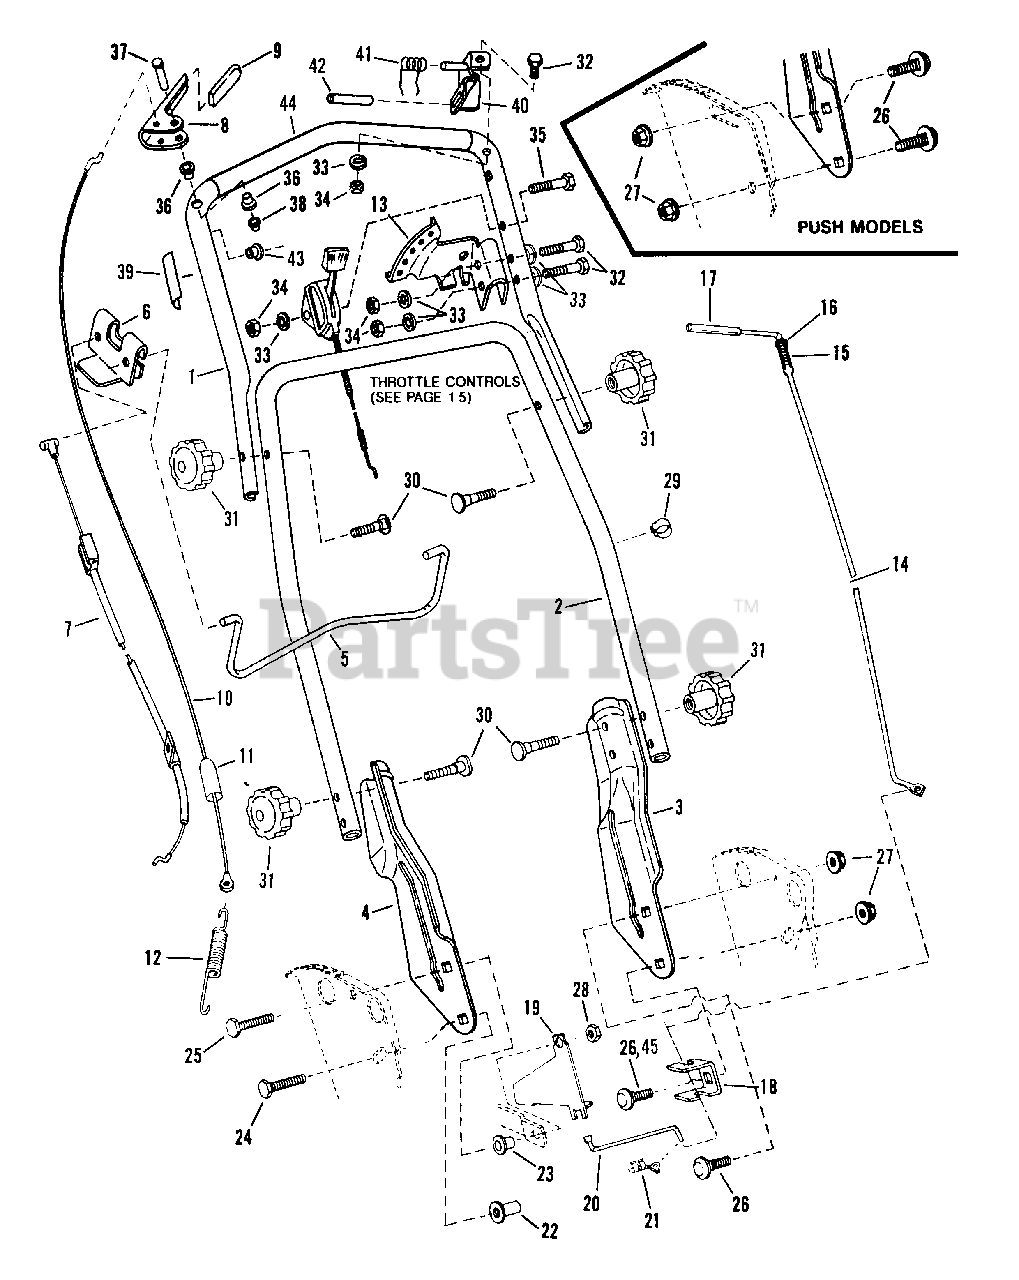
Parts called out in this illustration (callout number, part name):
1	HANDLE, Upper
2	HANDLE, Middle
3	HANDLE, Lower Left Hand
4	HANDLE, Lower Right Hand
5	CONTROL, Blade
6	CLIP, Blade Control
7	CABLE, Blade Control
8	HANDLE, Wheel Drive
9	GRIP, Wheel Drive Handle
10	CABLE, Clutch Pull (Z-BEND)
11	COVER, Vinyl
12	SPRING, Clutch
13	SECTOR, Speed
14	LEVER, Speed Control
15	SPRING, Speed Control
16	WASHER, 3/8" Flat
17	GRIP, Speed Control Handle
18	ANCHOR, Speed Control
19	GUIDE, Lower V-Belt
20	ROD, Transfer
21	CLIP, Transfer Rod
22	TEE-NUT, 5/16-18
23	BUSHING, Differential
24	BOLT, 5/16-18 x 3/4 Flange Lock
25	CAPSCREW, 5/16-24 x 1
26	BOLT, 5/16-18 x 5/8 Carriage
27	NUT, 5/16-18 Hex Flange Lock
28	NUT, 5/16-24 Center Lock
29	CLIP Cable/Wiring
30	SCREW,5/16-18 x 1-7/8 Curved Head
31	KNOB, 5/16-18
32	CAPSCREW, 1/4-28 x 1-3/8
33	LOCKWASHER, 1/4 Internal Tooth
34	NUT, 1/4-20 Hex
35	CAPSCREW, 1/4-28 x 1-3/4
36	BUSHING
37	PIN, Clutch Handle
38	PUSH-NUT
39	DECAL, Blade Control
40	ASSEMBLY, Blade Control Bracket
41	SPRING, Blade Control
42	GRIP, Pivot
43	BUSHING
44	GRIP, Foam
45	BOLT, 5/16-18 x 5/8" Carriage
